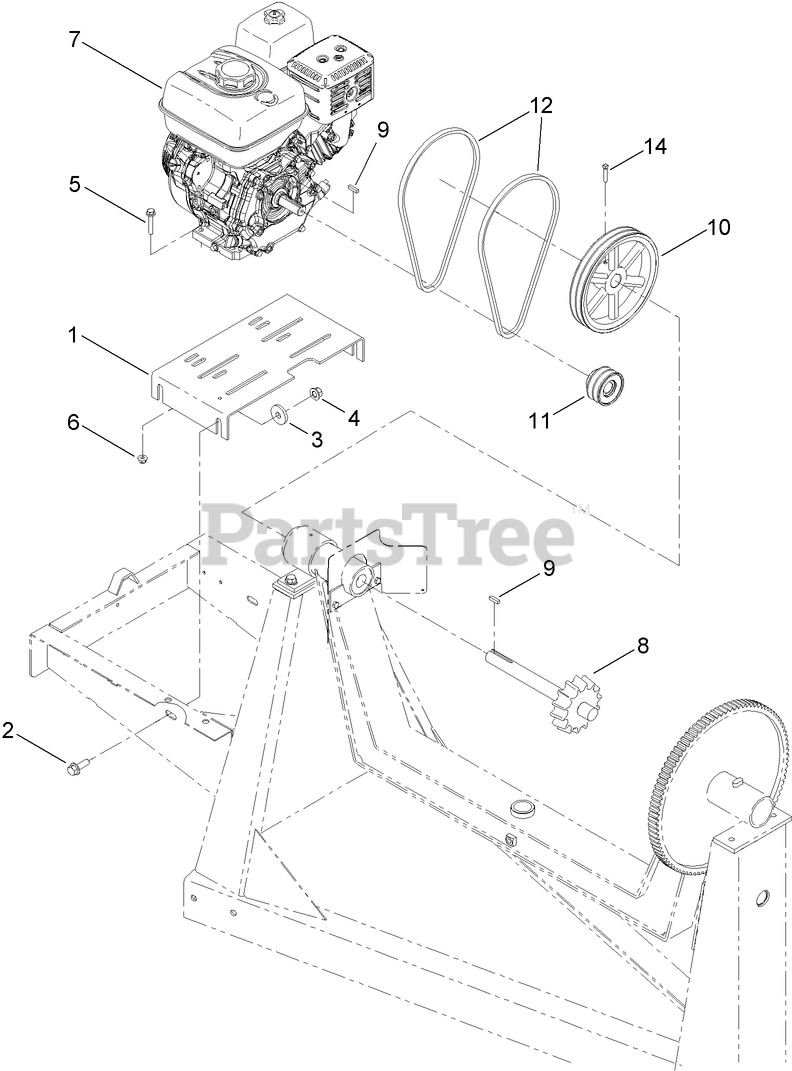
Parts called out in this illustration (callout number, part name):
1	BASE-MOTOR
2	SCREW-HHF
3	WASHER-FLAT
4	NUT-LOCK
5	SCREW-HHF
6	NUT-HF, NI
7	ENGINE-HONDA, GX240
8	SHAFT-DRIVE
11	SHEAVE
12	BELT-V
14	SCREW-SET
